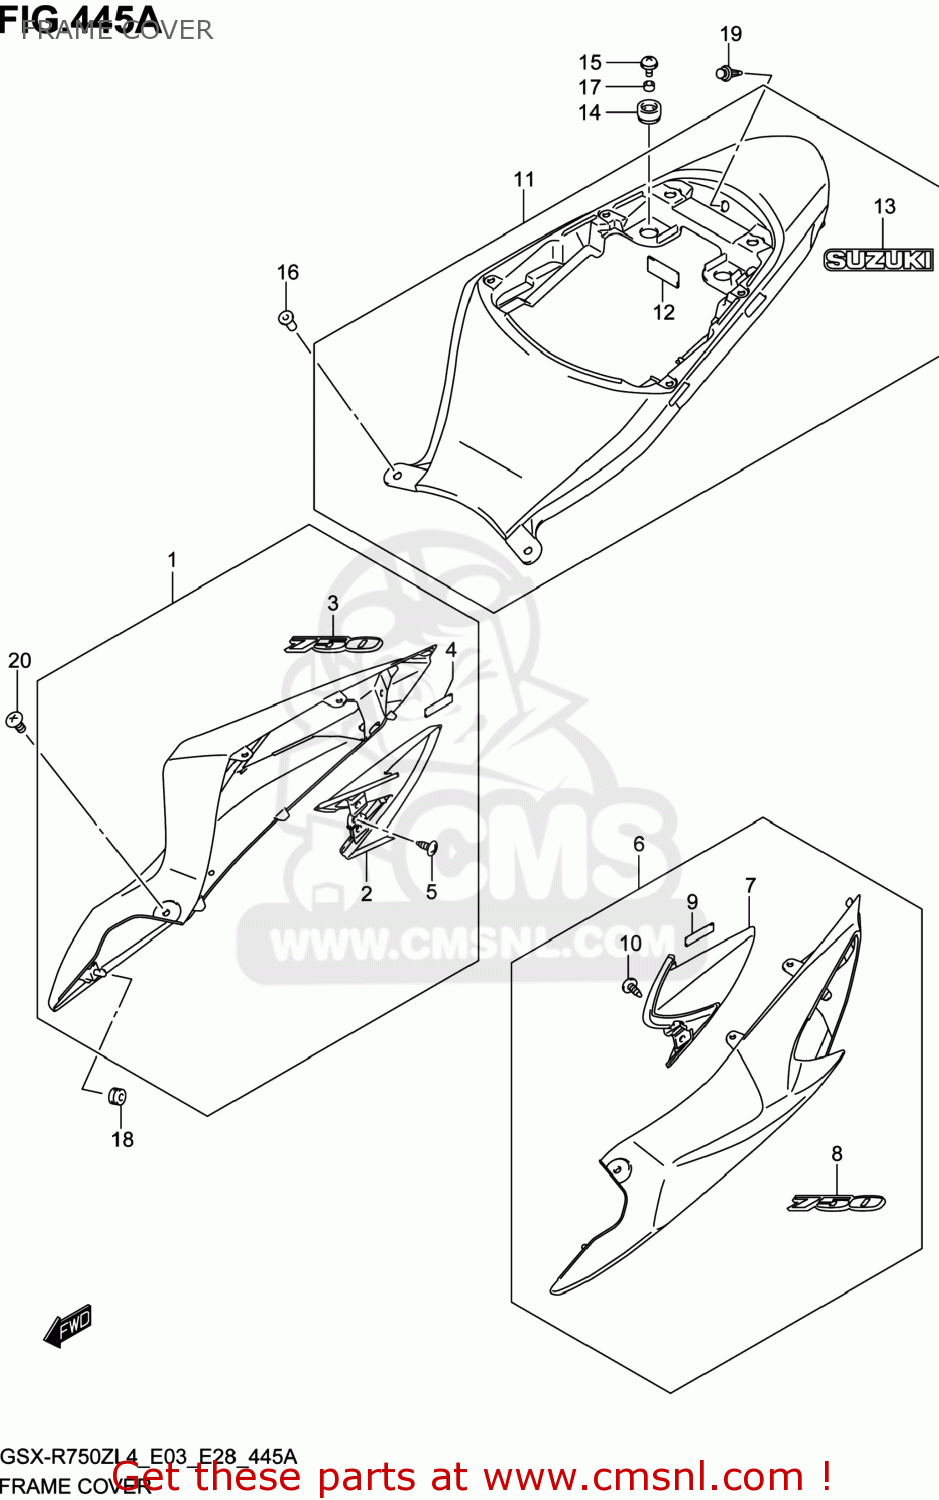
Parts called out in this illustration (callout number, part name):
1	COVER ASSY,FRAME,R(BLACK)
2	COVER,FRAME RR,R
3	EMBLEM,"750"
4	TAPE(6X25X0.13)
5	SCREW
6	COVER ASSY,FRAME,L(BLACK)
7	COVER,FRAME RR,L
8	EMBLEM,"750"
9	TAPE(6X25X0.13)
10	SCREW
11	COVER ASSY,FRAME CTR
12	CUSHION
13	TAPE(6X25X0.13)
14	CUSHION,FRAME COVER RR
15	SCREW(6X16)
16	NUT
17	SPACER(6.5X10X7)
18	CUSHION
19	CLIP(BLACK)
20	SCREW
